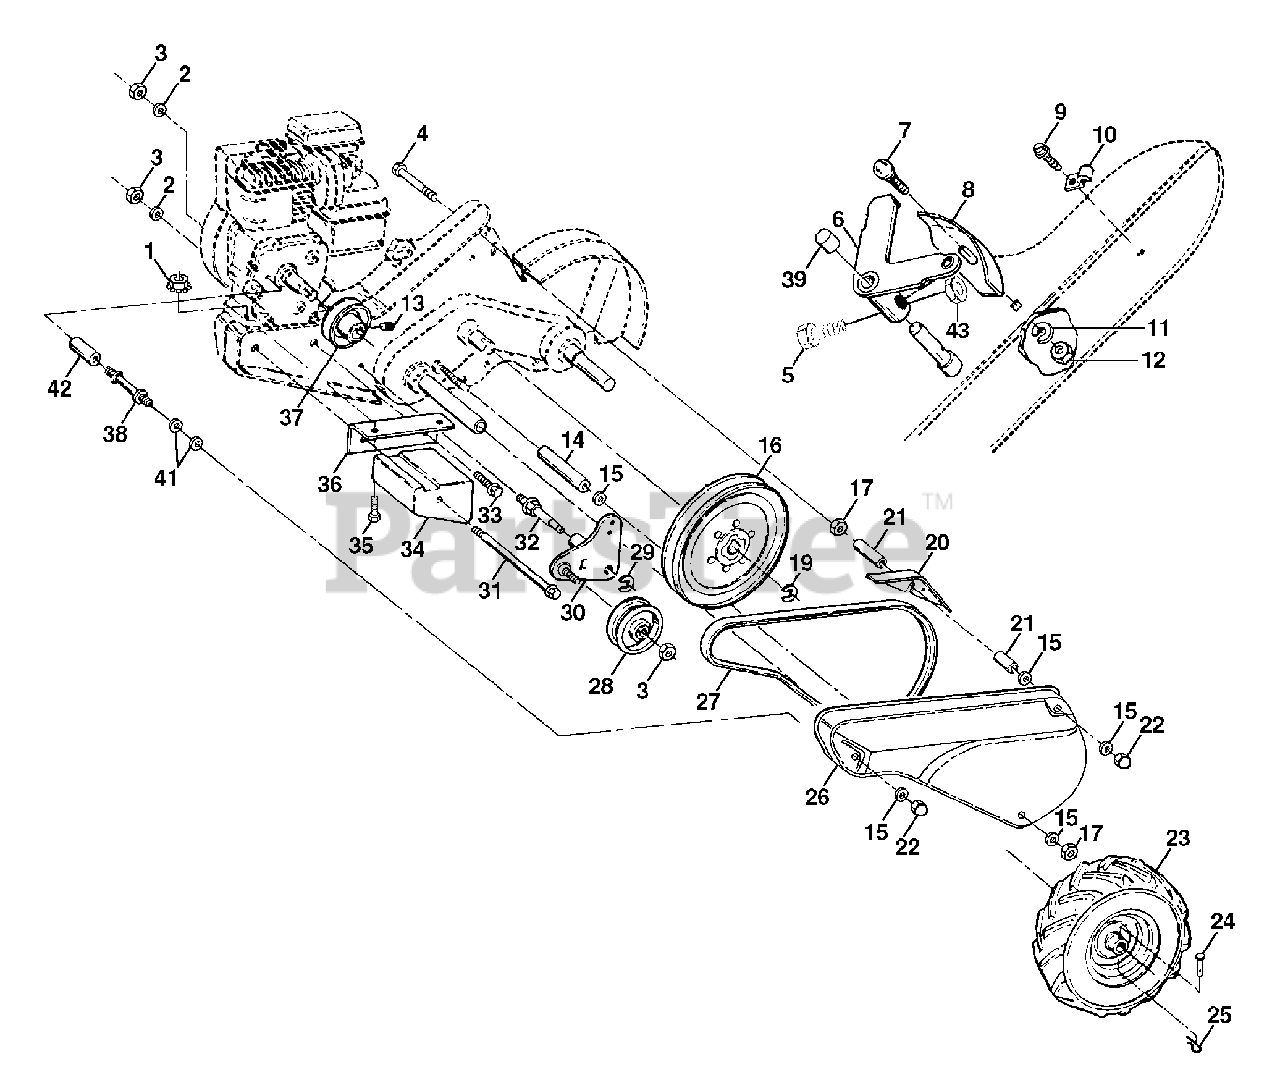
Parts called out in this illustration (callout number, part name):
1	Nut, Keps 5/16-18
2	Washer, Lock 3/8
3	Nut, Hex 3/8-16
4	Bolt, Hex 5/16-18 x 4-1/4
5	Screw, Shift Lever
6	Lever, Shift
7	Bolt, Carriage 1/4-20 x 1/2 Gr. 5
8	Plate, Shift Indicator
9	Screw, Hex, Washer Head, Slotted #10-24 x 1/2
11	Washer, Lock 1/4
12	Nut, Hex 1/4-20
13	Screw, Set, Hex 5/16-18 x 3/8
14	Spacer, Split 0.327 x 0.42 x 2.68
15	Washer 11/32 x 11/16 x 16 Ga.
16	Sheave, Transmission
17	Nut, Hex 5/16-18
19	Retainer, Ring
20	Guard, Pinch Point
21	Spacer, Split 0.327 x 0.42 x 1.688
22	Nut, Cap 5/16-18
23	Rim
23	Tire Valve
24	Rivet, Drilled
25	Clip, Hairpin
26	Guard, Belt
27	Belt, V
28	Pulley, Idler
29	Ring, Klip
30	Bracket, Idler
31	Bolt, Hex 5/16-16 x 12
32	Shaft, Idler Arm
33	Bolt, Hex 3/8-16 x 1
34	Counterweight, L. H.
35	Bolt, Hex 5/16-18 x 1 1/2
36	Bracket, Reinforcement, L. H.
37	Sheave, Engine
38	Stud, Belt Guard
39	Cap, Plunger Blk
41	Washer 11/32 x 1 x 10 Ga.
43	Nut, Lock #10-24
